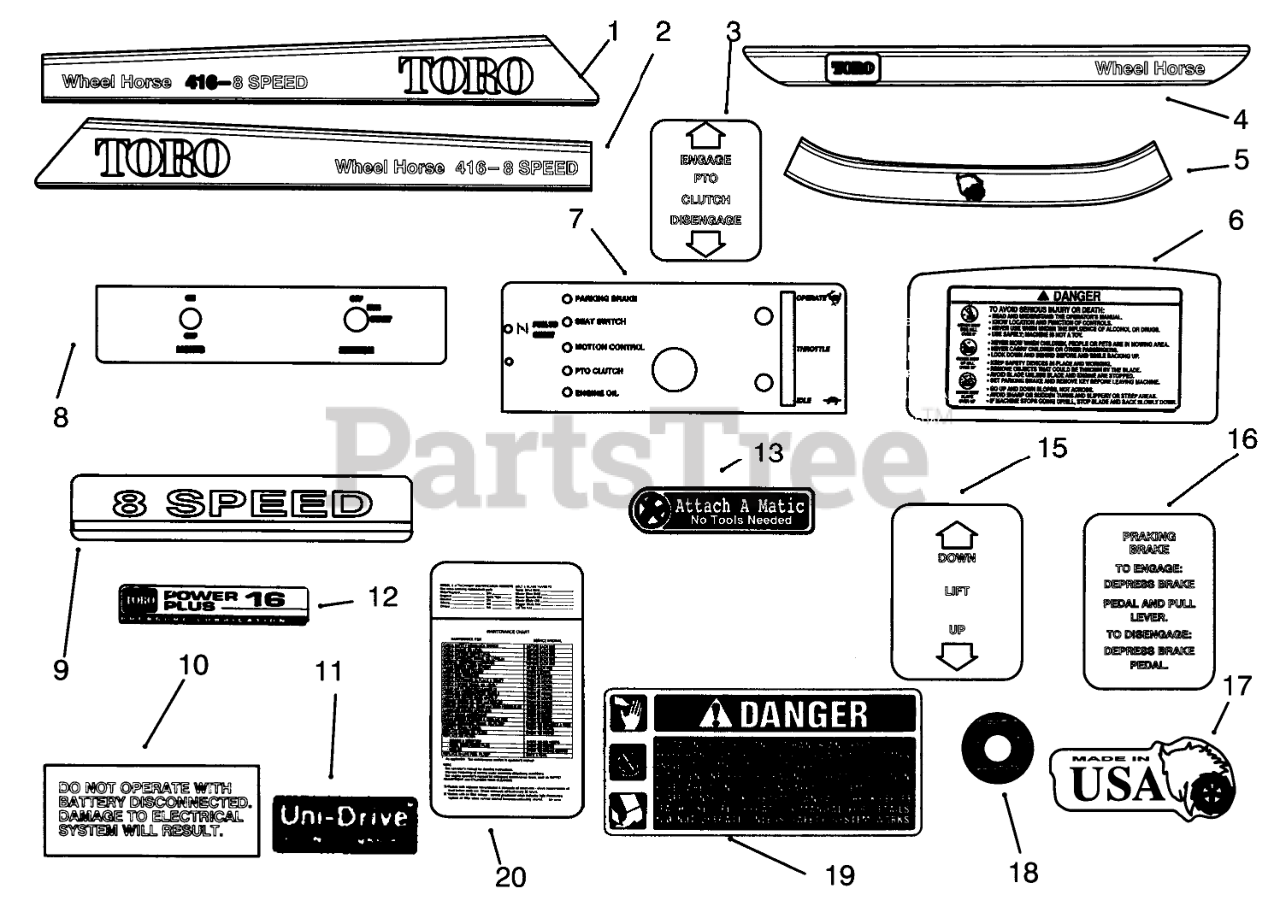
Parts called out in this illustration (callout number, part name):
1	DECAL-HOOD 416-8 L H
2	DECAL-HOOD 416-8 R H
3	DECAL PTO CLUTCH
4	DECAL-FENDER
5	DECAL-FRONT HOOD
6	Decal-Danger
7	DECAL-LOWER DASH
8	DECAL-BACK PLATE
9	DECAL-MODEL 8-SPEED
10	DECAL ELECT SYSTEM
11	Decal-Unidrive
12	DECAL-PWR PLUS 16 PL
13	Decal-Attac-O-Matic
15	DECAL-LIFT
16	DECAL-PARKING, BRAKE
17	Decal-Made In USA
18	Decal-Air Cleaner
19	DECAL-DANGER
20	Decal-Maintenance
